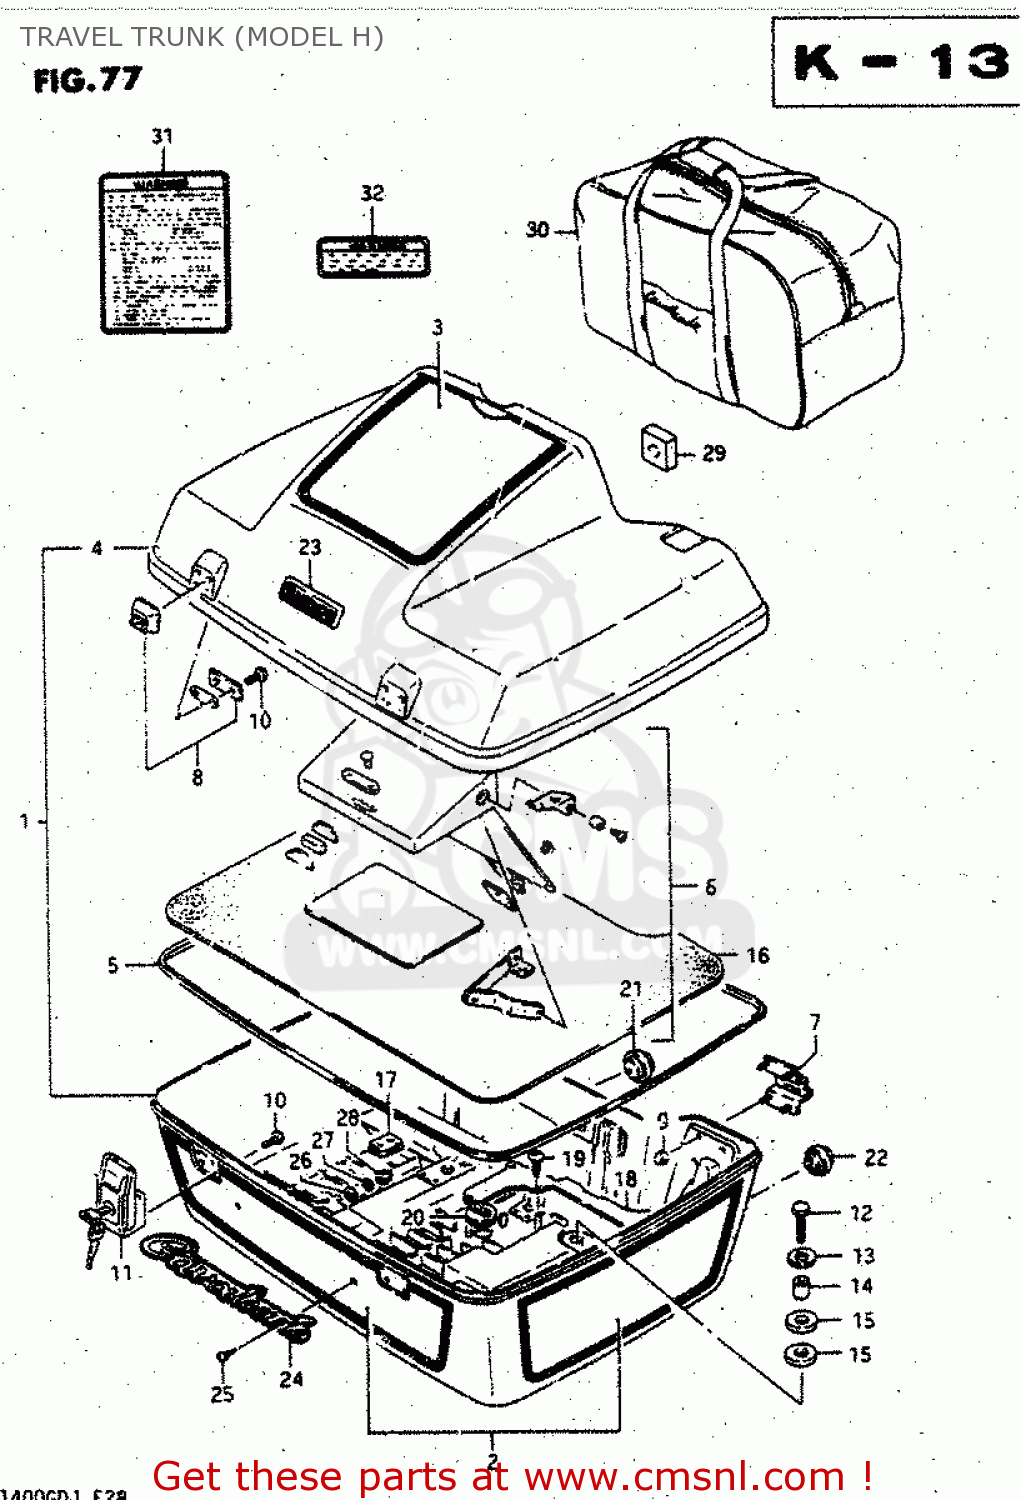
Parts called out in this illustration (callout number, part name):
1	TRUNK ASSEMBLY,TRAVEL
2	TAPE SET,TRAVEL TRUNK
3	TAPE SET,TRUNK LID STRIPE
4	LID,TRAVEL TRUNK
5	SEAL,TRAVEL TRUNK LID
6	MIRROR,TRAVEL TRUNK
7	HINGE,TRAVEL TRUNK
8	PLATE,TRUNK LID LOCK
9	NUT
10	SCREW
11	LOCK ASSY, SIDE BAG
12	BOLT
13	WASHER
14	SPACER(6.3X9.3X16.5)
15	CUSHION
16	SEAT,TRAVEL TRUNK BODY
17	GROMMET
18	COVER, AIR HOSE
19	SCREW
20	GROMMET
21	GROMMET
22	GROMMET
23	EMBLEM,TRAVEL TRUNK,UPPER
24	EMBLEM,TRAVEL TRUNK,LOWER
25	SCREW
26	WASHER
27	WASHER
28	NUT
29	SEAL
30	LUGGAGE BAG,TRAVEL TRUNK
31	LABEL (WARNING TRAVEL T
32	LABEL, WARNING
